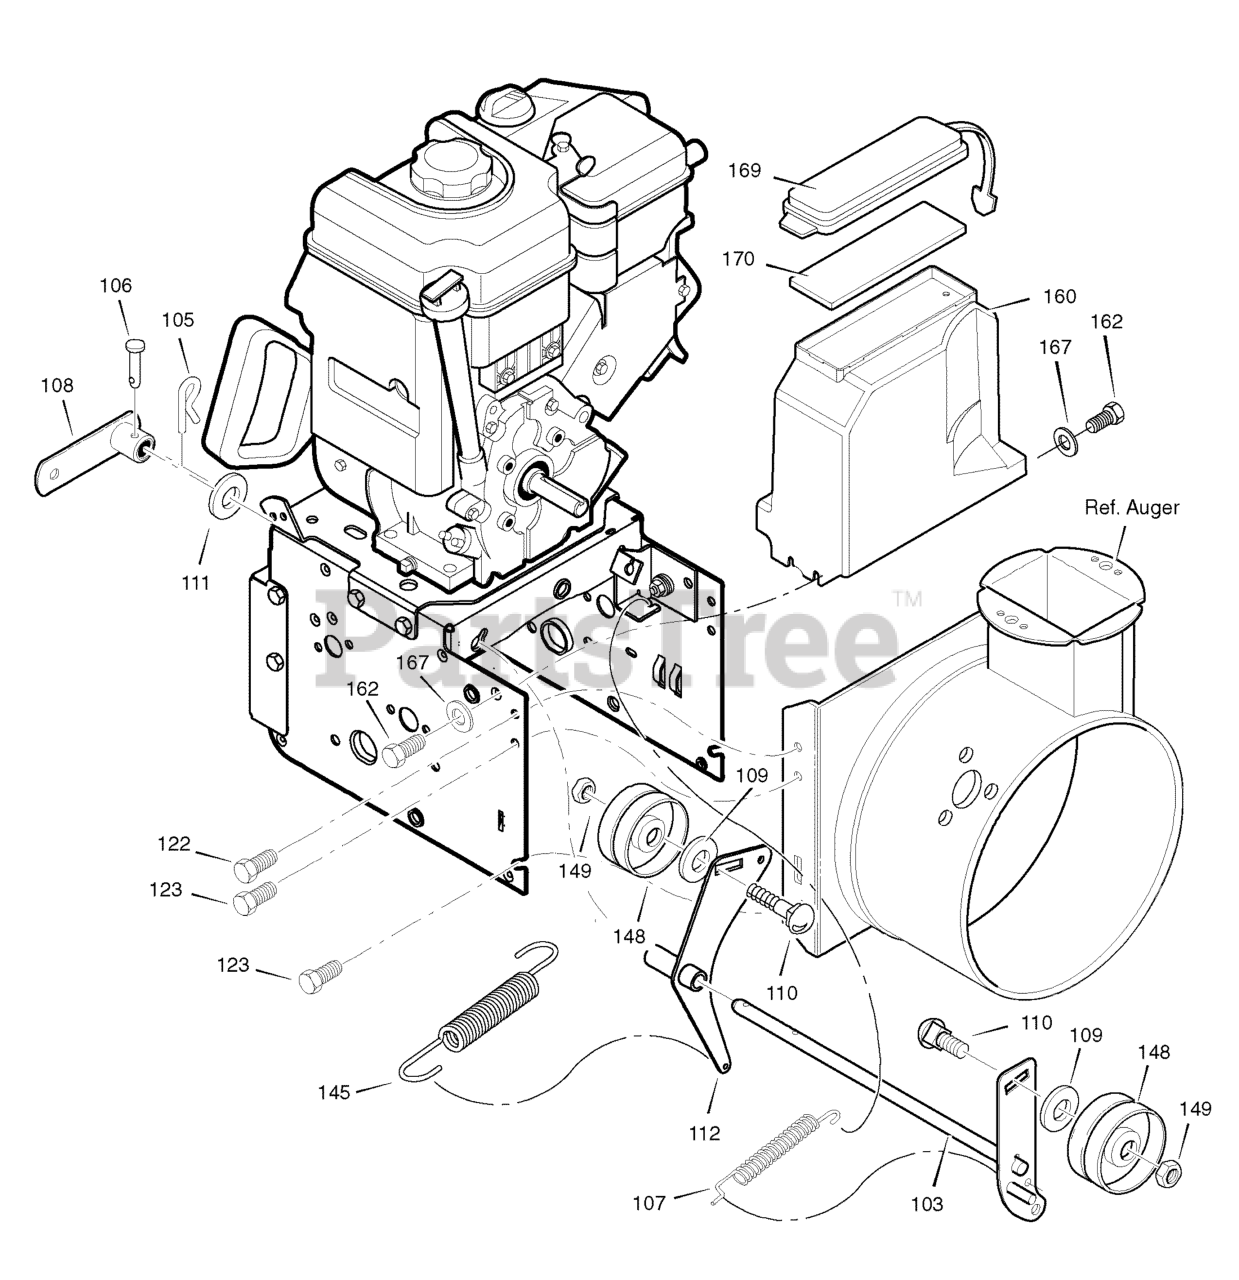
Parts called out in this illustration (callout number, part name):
103	IDLER ASSEMBLY, AUGER
105	PIN, HAIR .38DIA X 1.64LG
106	PIN, CLEVIS 3/16" DIA
107	SPRING, TENSION
108	SPRING ATTACH ASSEMBLY
110	BOLT, 3/8-16X1.25 CARRIAGE
111	WASHER, FLAT
112	BRACKET, IDLER
122	SCREW, TAP 5/16-18 X 0.50
123	SCREW, TAP 5/16-18 X 0.75
145	SPRING, CLUTCH
148	PULLEY, IDLER
149	NUT, JAM 3/8-16
160	COVER, BELT
162	SCREW, TAP
167	WASHER, FLAT
169	LID, TOOL BOX
170	PAD, FOAM
